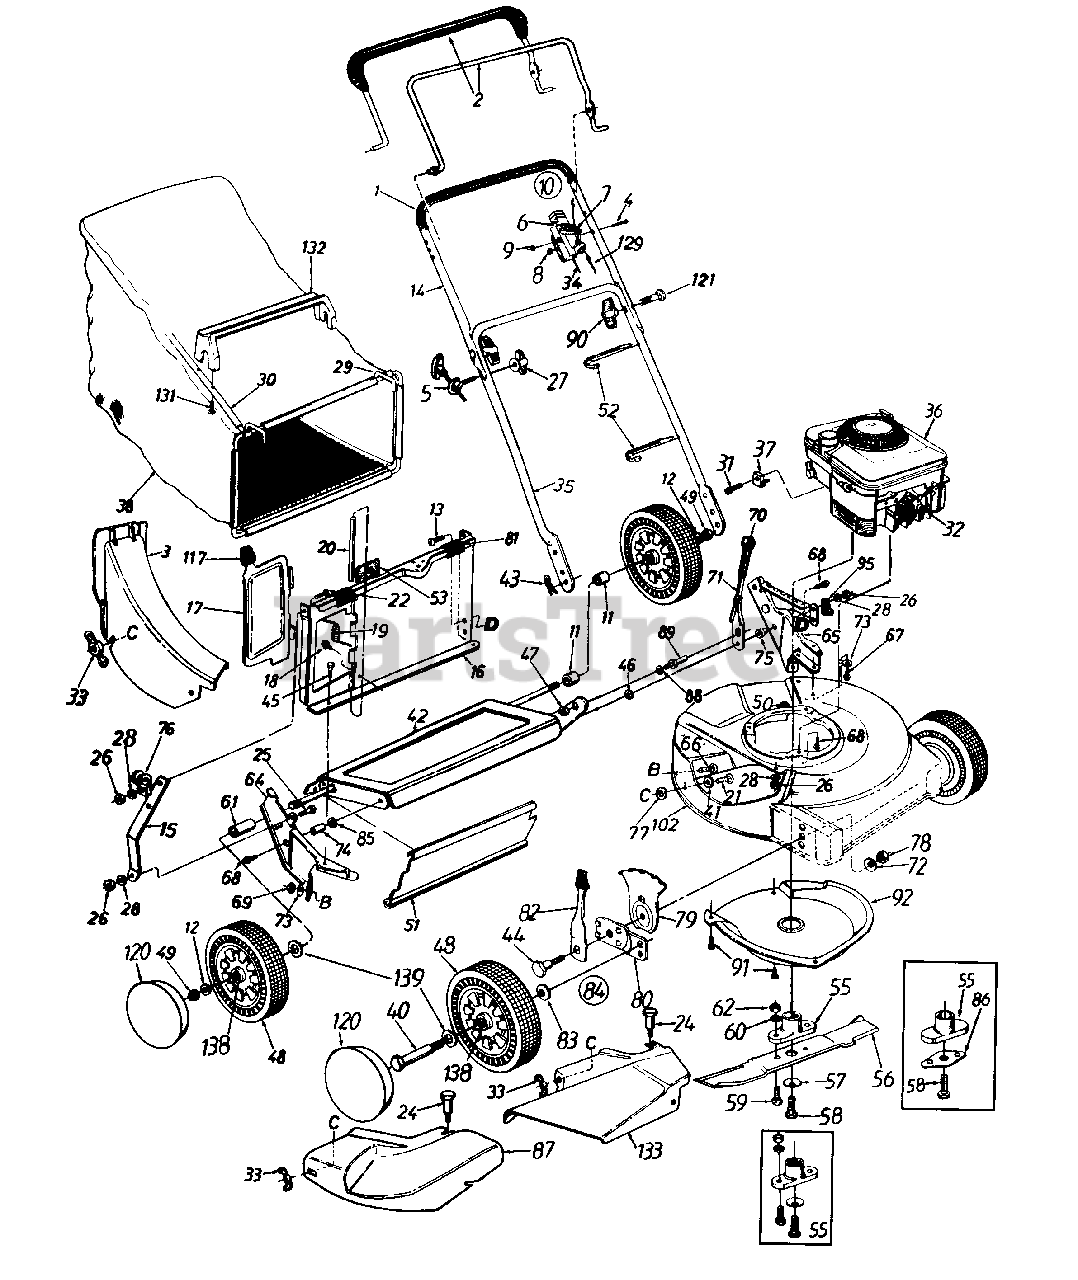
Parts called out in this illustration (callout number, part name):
1	Grip
3	Top Discharge Chute Ass'y.
4	Oval C-Sunk Scr.
5	Rope Guide
6	Throttle Body
7	Throttle Lever
8	Spr. Wash. .66" I.D.
9	Hex L-Nut 1/4-20 Thd.
10	Throttle Box Comp.
11	Spacer .526" I.D. x .690" O.D. x .640" Lg.
12	Fl-Wash. .510" I.D. x .75"
13	Truss Mach. Scr. 1/4-20 x .62"
19	Torsion Spring
20	Pivot Pin
21	Carriage Bolt 1/4-20 x .62"
22	Truss Mach. Scr. 1/4-20 x .75"
24	Shoulder Bolt .312" Dia. x .18" Lg. Special
25	Hex Bolt 1/4-20 x .62" Lg.
26	Hex Nut 1/4-20 Thd.
27	Handle Knob 1/4-20 Thd.
28	L-Wash. 1/4" I.D.
31	Hex Self-Tap Scr. #10-32 x .62"
32	Spark Plug lnsulator
33	Wing Nut w/Washer
34	Throttle Control Wire 61"
36	Engine
37	Cable Clamp
38	21" Top Discharge Grass Bag
40	Shld. Bolt .498" Dia. x 1.45"
41	Fl-Wash. .344" I.D. x .62"
44	Shld. Bolt .5" Dia. x .357"
45	Hex AB-Tap Scr. 1/4 x .62"
46	Fl-Wash. .38" I.D. x 1.0"
47	Hex Jam Nut 3/8-24 Thd.
48	Wheel Ass'y. Comp. (w/o Ball Bearings)
49	Hex L-Nut 1/2-20 Thd.
51	Rear Flap
52	Cable Tie
53	Foam Strip 1" Lg.
55	Blade Adapter Kit
56	21" Blade
57	Bell-Wash. .39" I.D.
58	Hex Bolt 3/8-24 x 1.5" Lg.
59	Hex Bolt 3/8-24 x 1" Lg.
60	L-Wash. 3/8" I.D.
61	Sleeve .526" I.D. x .69"
62	Hex Nut 3/8-24 Thd.
67	Hex Wash. Hd. B-Tap Scr. 5/16-18
68	Hex Wash. Hd. TT-Tap Scr. 3/8-16
69	Hex Nut 5/16-18 Thd.
71	Height Adj. Lever
72	Bell-Wash. .39" I.D. x 1.38" O.D.
73	Bell-Wash. 5/16" I.D.
74	Spacer.383" I.D. x .503" O.D.
75	Shld. Spacer .500" Dia.
76	Rope Guide
77	Bolt Retainer 1/4 x .50" O.D.
78	Hex Nut 3/8-16 Thd.
79	Height Adj. Plate
80	Pivot Bar
81	Panel Clip
82	Spring Lever Ass'y. w/Knob
83	Bell-Wash. .38" I.D. x .88" O.D.
84	Height Adj. Ass'y. Comp.- R.H.
85	Fl-Wash. 3/8" I.D. x 1" O.D.
86	Blade Bell Support
87	Mulching Plug
88	L-Wash. 3/8" I.D.
89	Shld. Pin 3/8-24 x 1.43" Lg.
90	Hand Knob
91	Hex Wash. Hd. Tap Scr. 1/4 x .38" Lg.
120	Hub Cap
121	Curved Hd. Bolt 5/16-18 x 2" Lg.
129	Control Cable - 44" Lg.
131	Hex AB-Tap Scr. #12 x 1.0"
132	Bag Handle
133	Side Chute Deflector Ass'y.
138	Ball Bearings 2 Req'd. Per Wheel
139	Wave Washer
